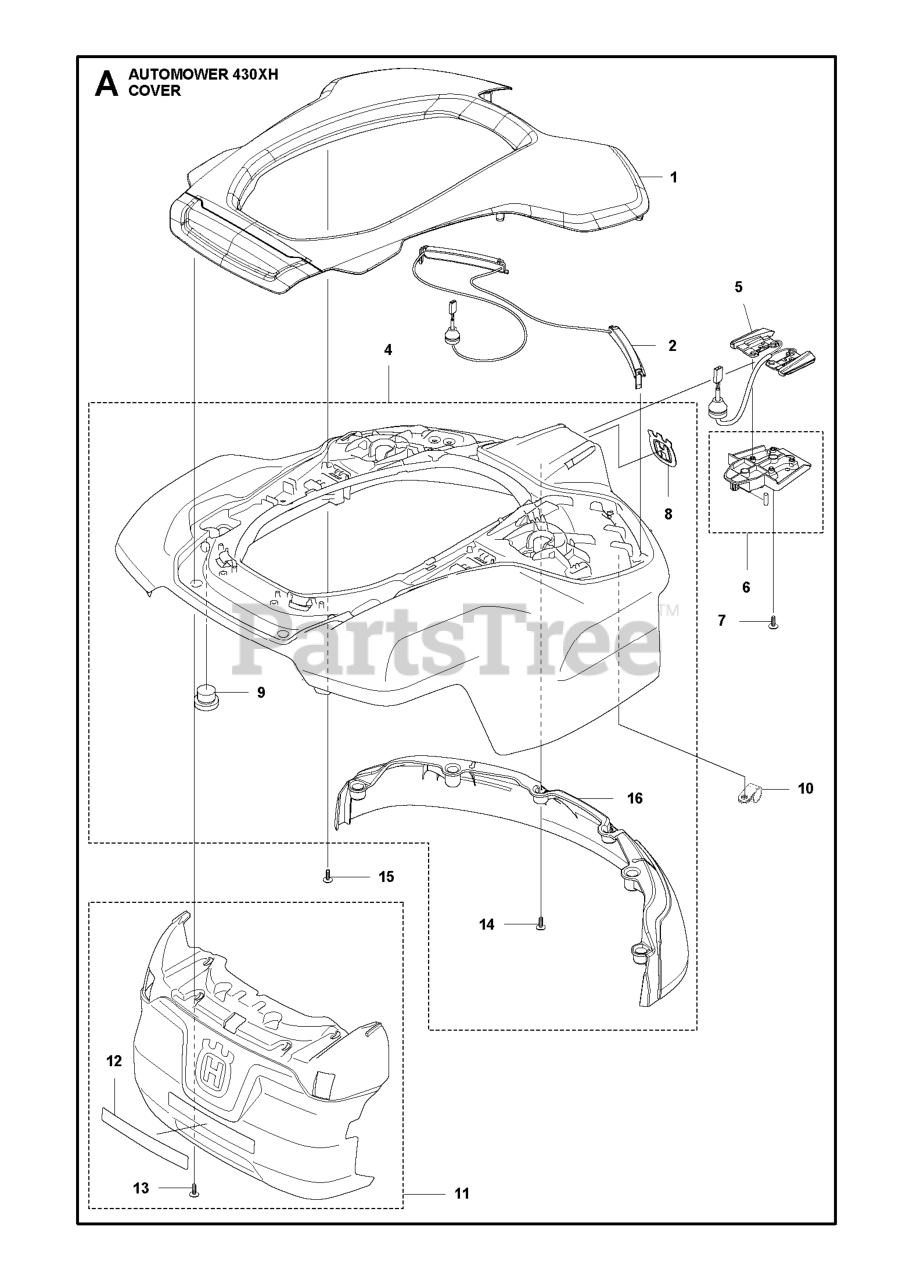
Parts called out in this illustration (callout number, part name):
1	BODY KIT GREY 430X 2018+
1	BODY KIT WHITE 430X 2018+
1	BODY KIT ORANGE 430X 2018+
2	WIRING ASSY LED
4	BODY ASSY 430XH, 450XH
5	CABLE ASSY CHARGING PLATE
6	HOLDER ASSY 430XH, 450XH
7	SCREW 14MM
8	DECAL HUSQVARNA CROWN HEIGHT 5
9	CAP SNAPLOC
10	CLAMP P-CLIP
11	BUMPER ASSY 430XH,450XH,550H
12	LABEL WARNING P15
13	SCREW ITXPANT
14	SCREW ITXPANT
15	SCREW ITXPANT
16	BUMPER FRONT
